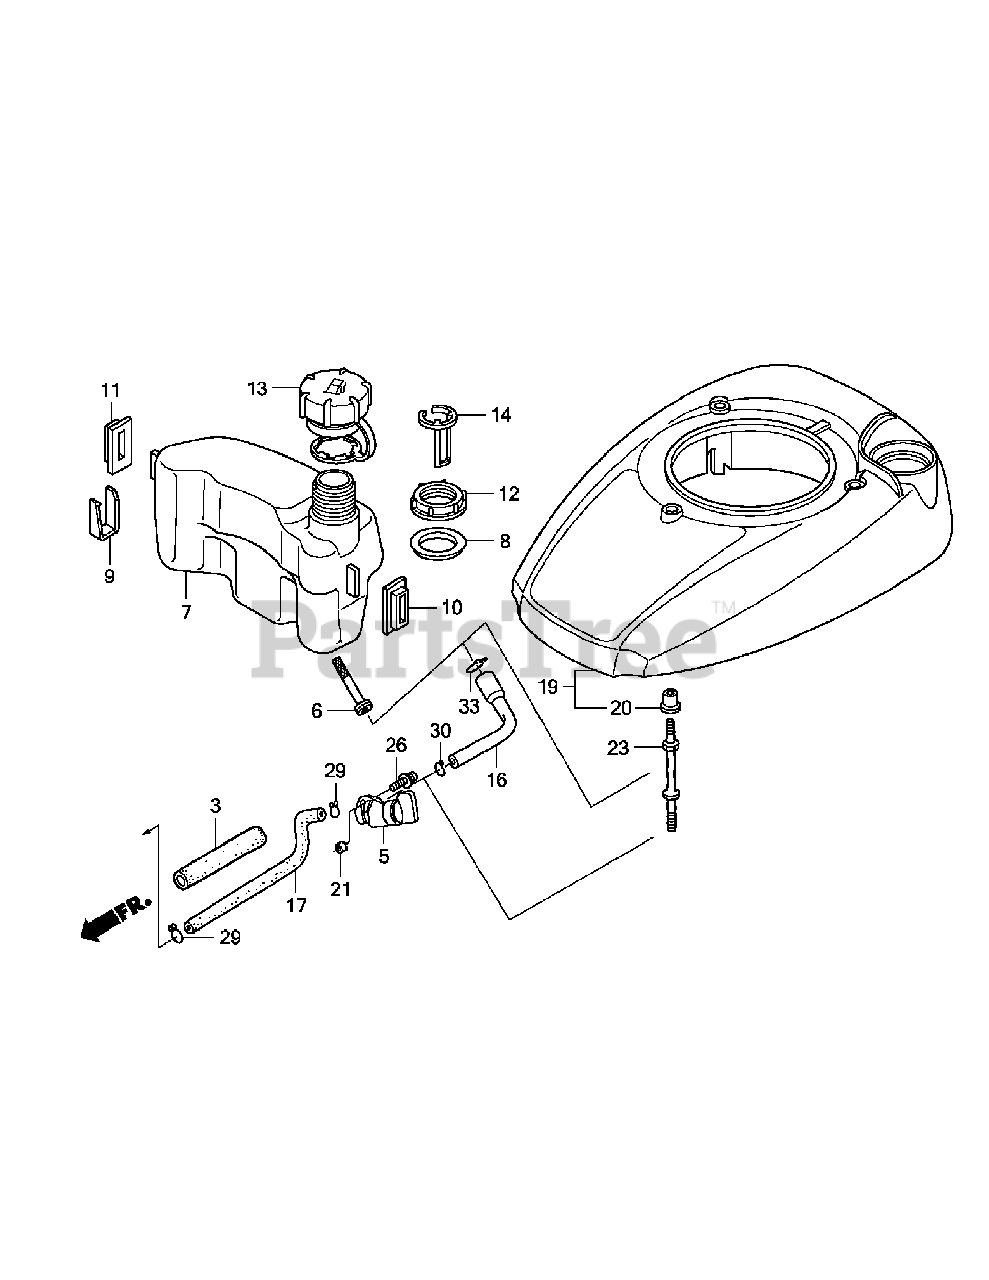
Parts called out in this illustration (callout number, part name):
3	Rubber, Supporter (107mm)
5	Petcock Assy.
6	Filter, Fuel
7	Tank, Fuel
8	Seal, Fuel Filler Neck
9	Clip, Tank Mounting.
10	Rubber A, Tank Mounting
11	Rubber B, Tank Mounting
12	Nut, Tank Mounting
13	Cap Assy., Fuel Tank.
14	Gauge, Fuel Level
16	Tube, Fuel Tank
17	Tube, Fuel
19	Cover, Fan *nh1* (Black)
20	Collar, Fan Cover
21	Collar, Fuel Petcock
23	Bolt, Stud (H=42.5mm)
26	Screw-washer (5x10)
29	Clip, Tube (B8)
30	Clip, Tube (B10)
33	Clip, Tube (C11)
